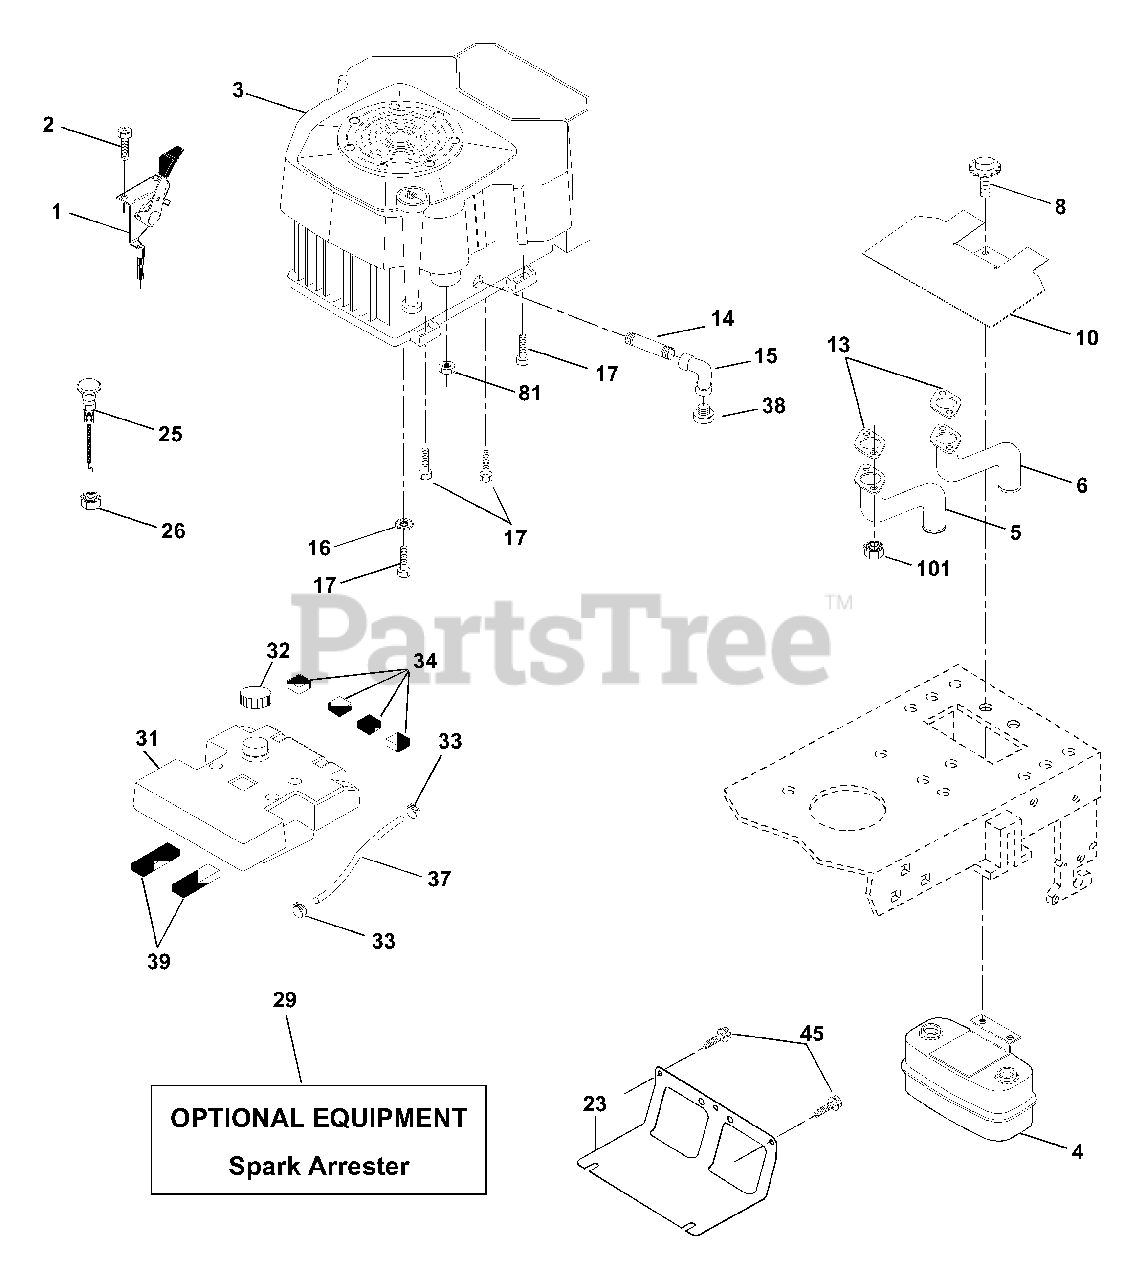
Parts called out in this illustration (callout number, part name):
1	Control Throt Flg 180 LH
2	Screw Hex Thd Cut 1/4-20x5/8 T
4	Muffler Asm Twin Lo-Tone
5	Pipe Exhaust CV18/20 LH
6	Pipe Exhaust CV18/20 RH
8	Bolt 5/16-18unc x 3/4 W/Sems
10	Shield Heat Muffler CV18/20
13	Gasket Kohler CV18-CV26
14	Nipple Pipe 3/8 Npt X 4-1/2"
15	Elbow Std 90 Degree 3/8-18 Npt
16	Washer Lock Ext Tooth 3/8
17	Screw Thdrol 3/8-16 x 1-1/2
23	Shield Browning
25	Choke Control 37"
26	Nut, Keps 3/8-24 Unf
29	Kit Spark Arrestor (Flat Scrn)
31	Tank Fuel 3 50 Rear
32	Cap Asm Fuel Top N/Lany Vented
33	Clamp Hose Blk
34	Pad, Spacer
37	Line Fuel 7.5
38	Plug Oil Drain
39	Pad, Idler
45	Screw 3/8-16 x 3/4
81	Nut Flange 1/4-20 Starter Nut
101	Nut Flange M8-1.25 Non-Lk Zinc
